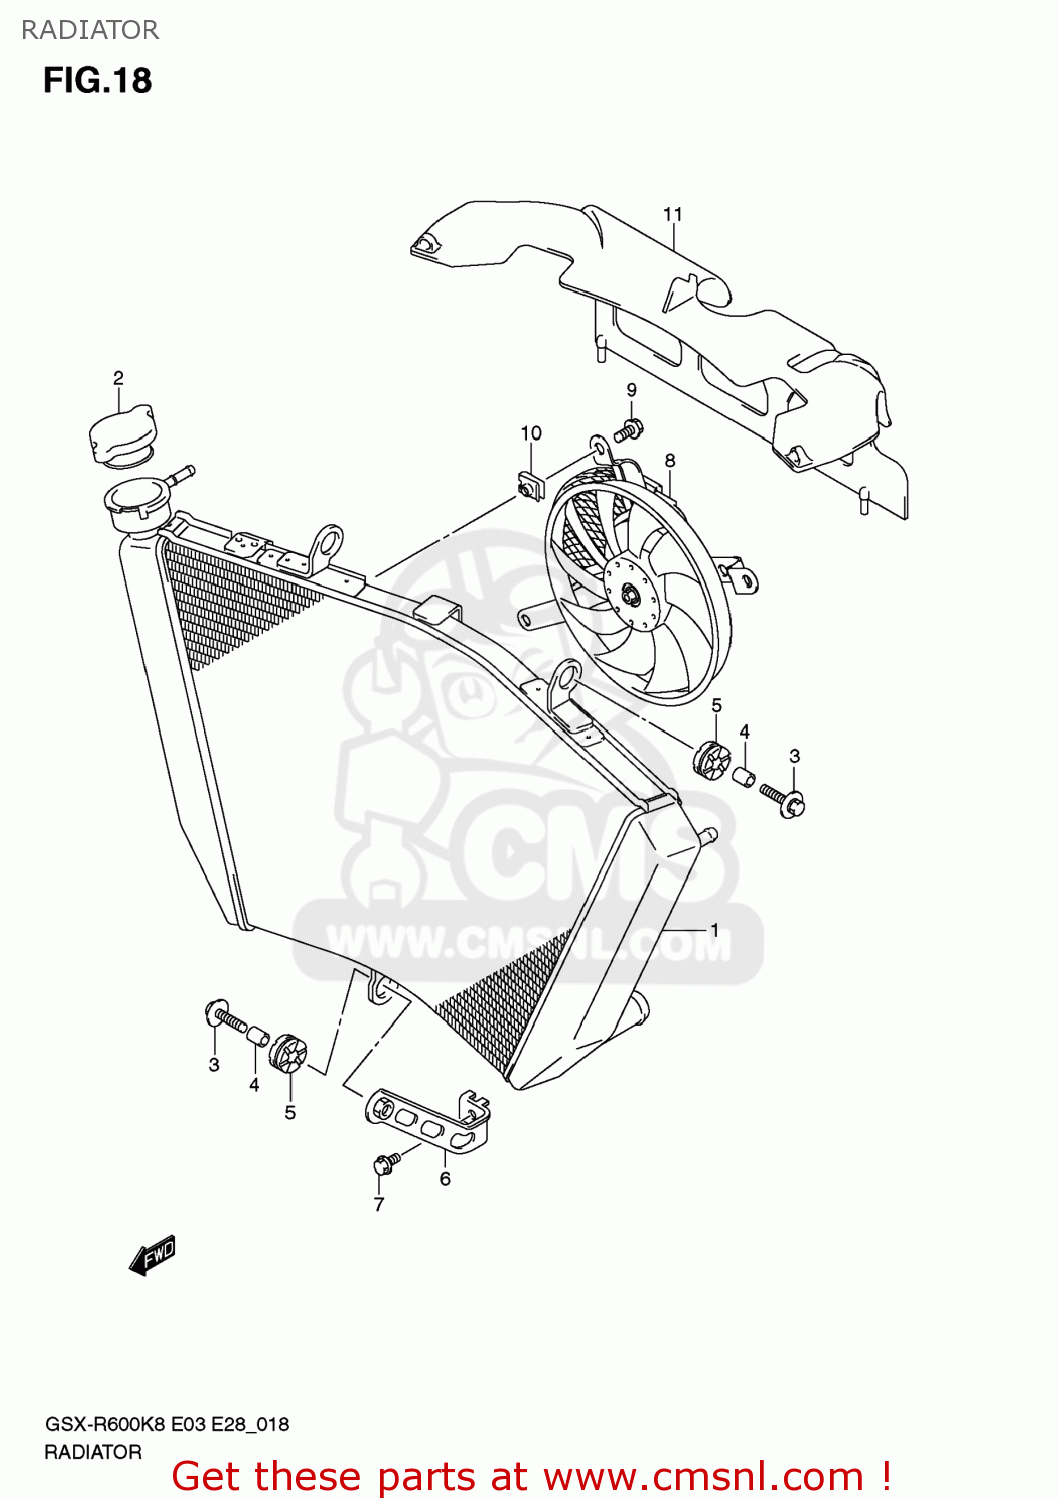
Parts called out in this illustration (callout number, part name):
1	RADIATOR ASSY,WATER
2	CAP,RADIATOR(1.1)
3	BOLT(6X25)
4	SPACER(6.5X10X12)
5	CUSHION
6	BRACKET,RADIATOR
7	BOLT
8	FAN ASSY,RADIATOR
9	BOLT,FAN ASSY
10	NUT,RADIATOR FAN
11	SHIELD,RADIATOR HEAT
